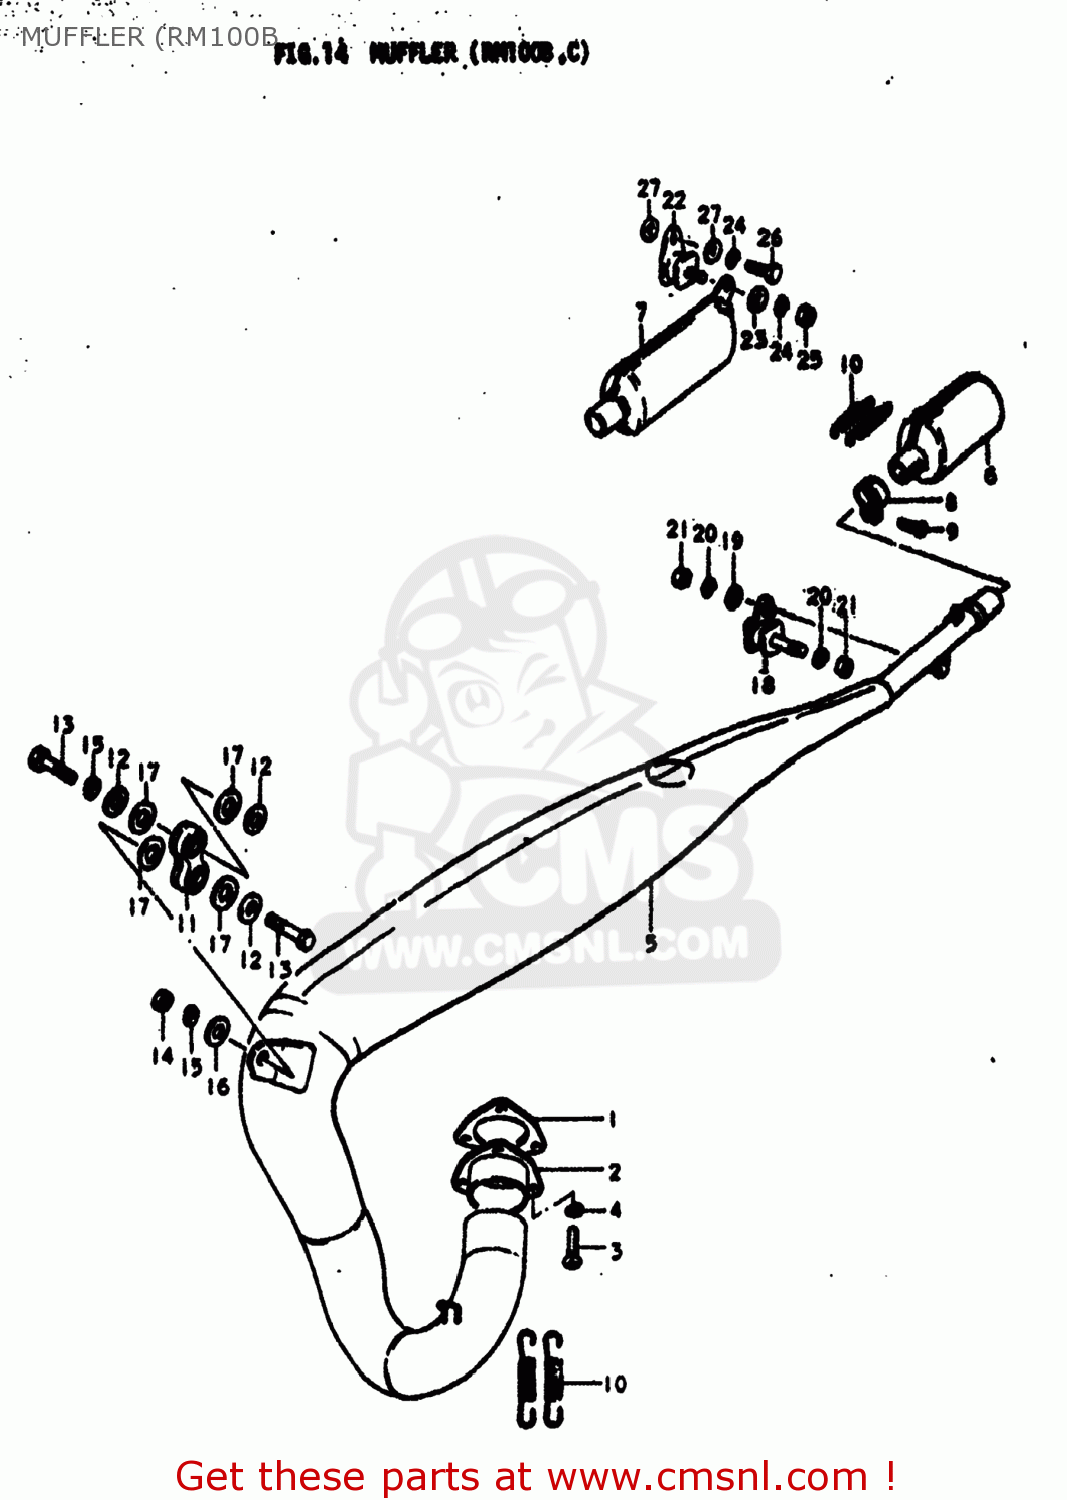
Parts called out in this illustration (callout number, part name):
1	GASKET,EXHAUST PIPE (MCA)
2	FLANGE,EXHAUST PIPE
3	SCREW
4	LOCK WASHER
5	BODY,MUFFLER
6	BODY,MUFFLER
7	BODY,MUFFLER
8	CLAMP
9	BOLT(6X20)
10	SPRING
11	DAMPER,MUFFLER
12	WASHER
13	BOLT
14	NUT
15	LOCK WASHER
16	WASHER
17	WASHER(13X28X1.6)
18	DAMPER,MUFFLER SUPPORT
19	WASHER
20	LOCK WASHER
21	NUT
22	DAMPER,MUFFLER SUPPORT
23	WASHER
24	LOCK WASHER
25	NUT
26	BOLT
27	WASHER (8.2X20X1.6)
